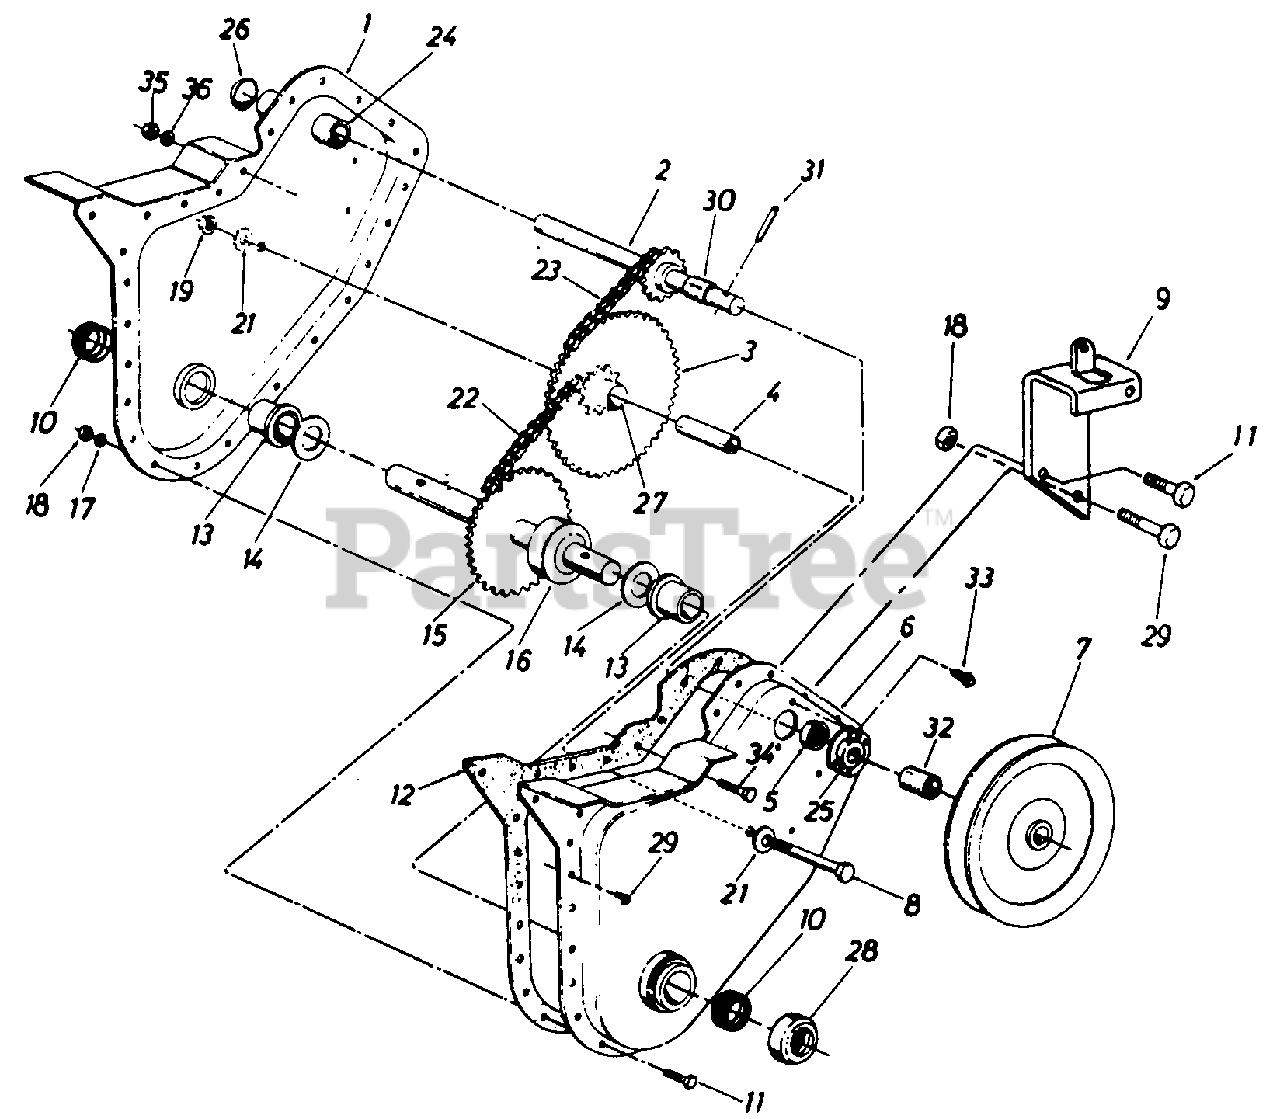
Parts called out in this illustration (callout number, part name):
1	HOUSING-CHAIN-CASE RH
2	SHAFT ASSY-INPUT
3	SPROCKET & HUB ASSY
4	BEARING-INNER RACE
5	BEARING-BALL
6	CHAIN CASE HSG-LH
8	SCREW-HEX 3/8-24 X 2.50
9	BRACKET-FUEL TANK
11	SCREW-HEX 1/4-28 X .62
12	GASKET
13	BEARING-FLANGE
14	WASHER-FL-.88 X 1.50 X .030
15	SHAFT ASSY-TINE
17	LOCK WASHER 1/4 DIA
18	NUT-HEX 1/4-28
19	NUT-HEX INS L-3/8-24
21	WASHER-BELL .3/8ID X 1.12OD X .030
22	#420 CHAIN 1/2 PITCH X 38 LINKS
23	#35 CHAIN 3/8 PITCH X 50 LINKS
25	Bearing Housing
26	PLUG-EXPANSION
27	BEARING-SLEEVE
29	SCREW-HEX WASH SF TAPP
31	PIN-SPRING SPIRAL 1/4X1.5 HEAVY DT
33	SCREW-TAP 1/4-20 X .38
34	SCREW-HEX 5/16-18 X .75
35	NUT-HEX 5/16-18
36	WASHER-LOCK-5/16
